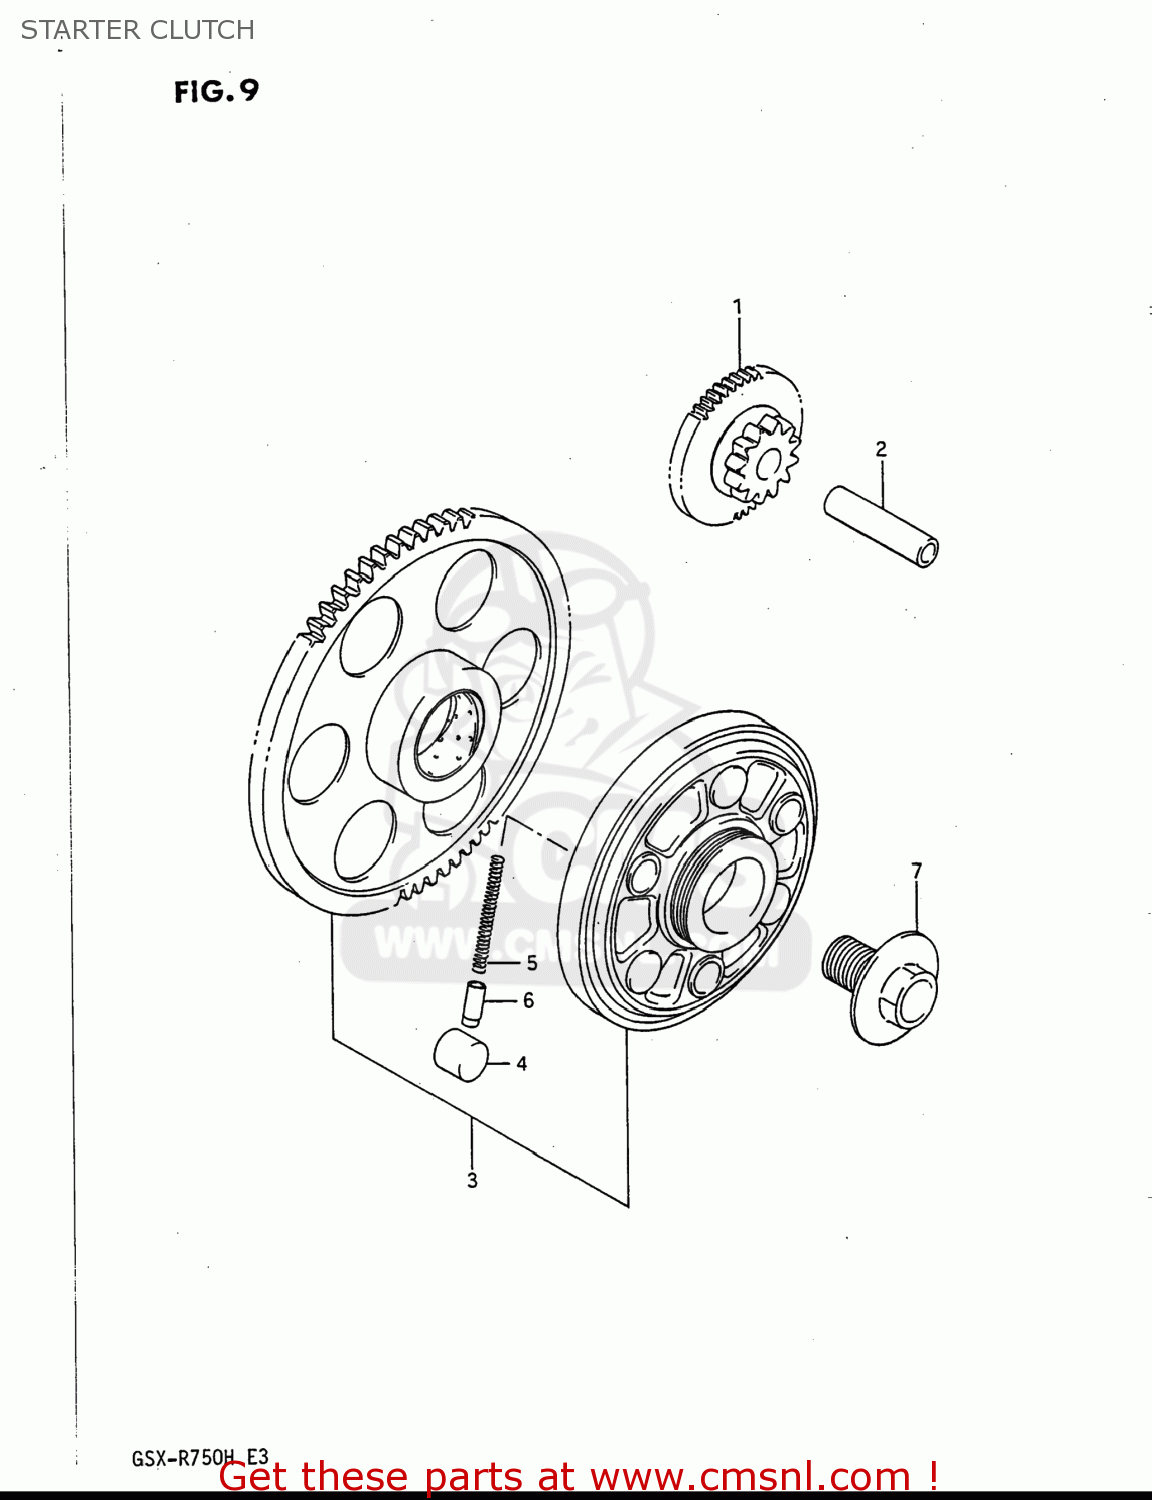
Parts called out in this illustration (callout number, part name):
1	GEAR,STARTER IDLE(NT:12,53)
2	PIN(7X11X42)
3	CLUTCH SET,STARTER
4	PIN(14X13)
5	SPRING
6	PIECE,PUSH
7	BOLT(14X21)
